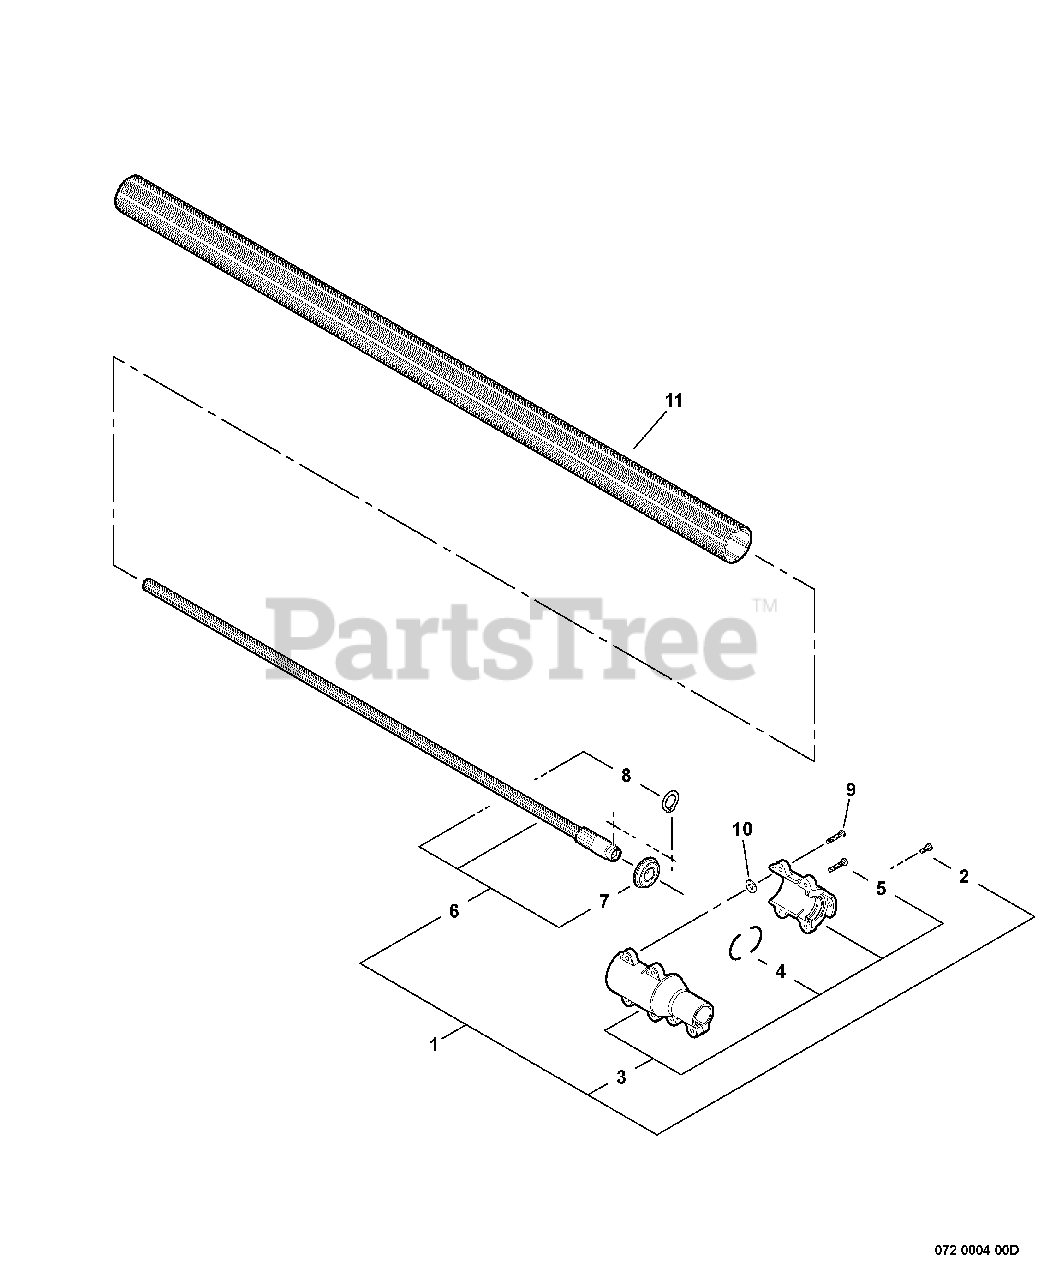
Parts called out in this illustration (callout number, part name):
1	DRIVESHAFT ASSY
2	SCREW - 5X14
3	COUPLING ASSY
4	CUSHION
5	SCREW - 5X20
6	DRIVESHAFT ASSY - LOWER
7	BEARING, BALL - 6002
8	RING, RETAINING
9	SCREW - 5X20
10	WASHER - 5
11	PIPE, MAIN - ORANGE
